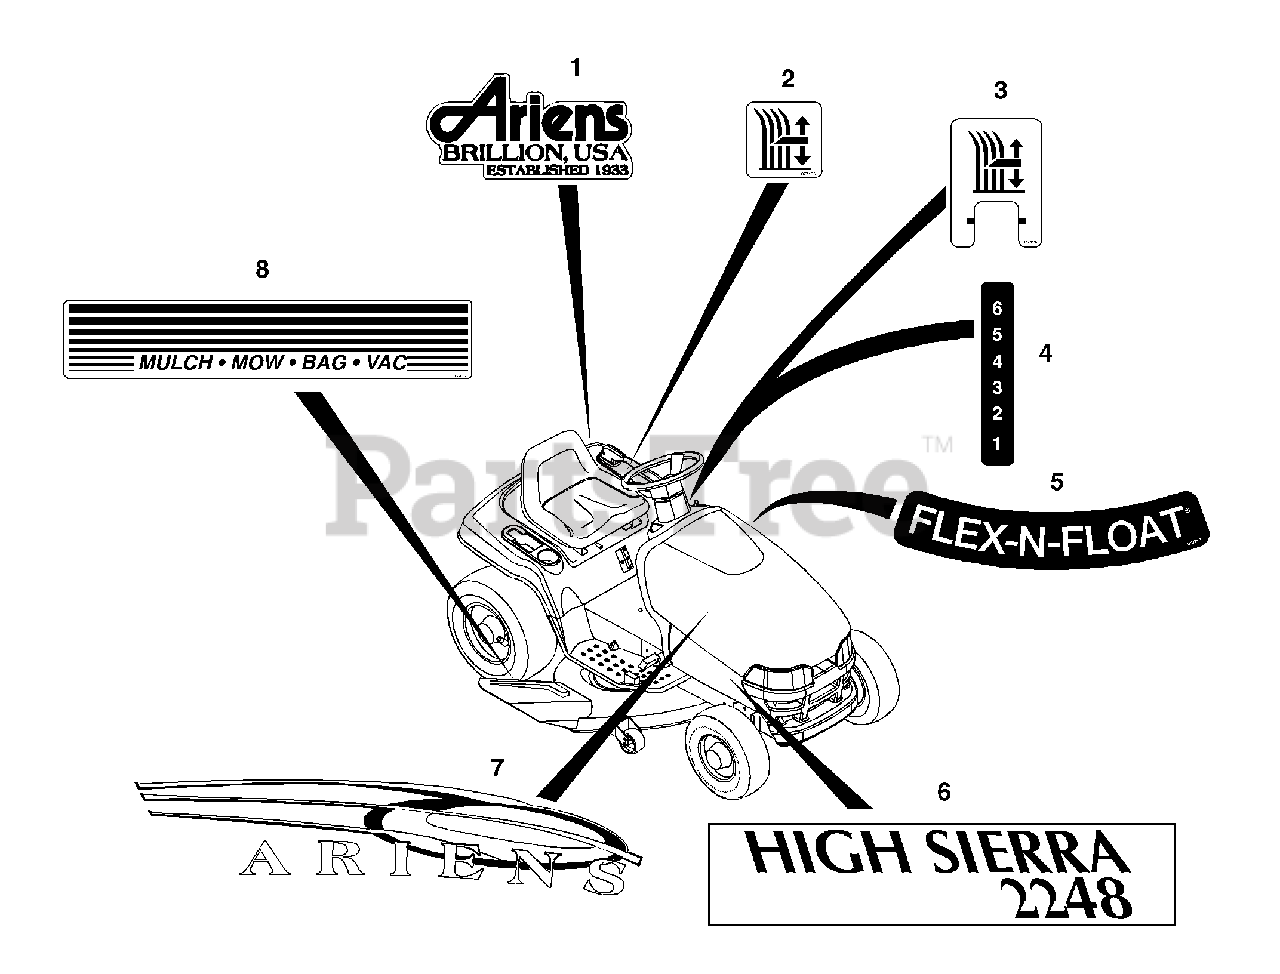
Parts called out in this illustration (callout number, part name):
1	DECAL- ARIENS EST. 1933
2	DECAL - CUT HEIGHT - INSERT
3	DECAL - CUT HEIGHT - FRAME
4	DECAL, INDICATOR
5	DECAL FLEX-N-FLOAT
6	DECAL-SIDE NUMERAL 2248
7	DECAL- ARIENS HOOD LOGO- R
8	DECAL- MULCH-MOW-BAG-VAC
